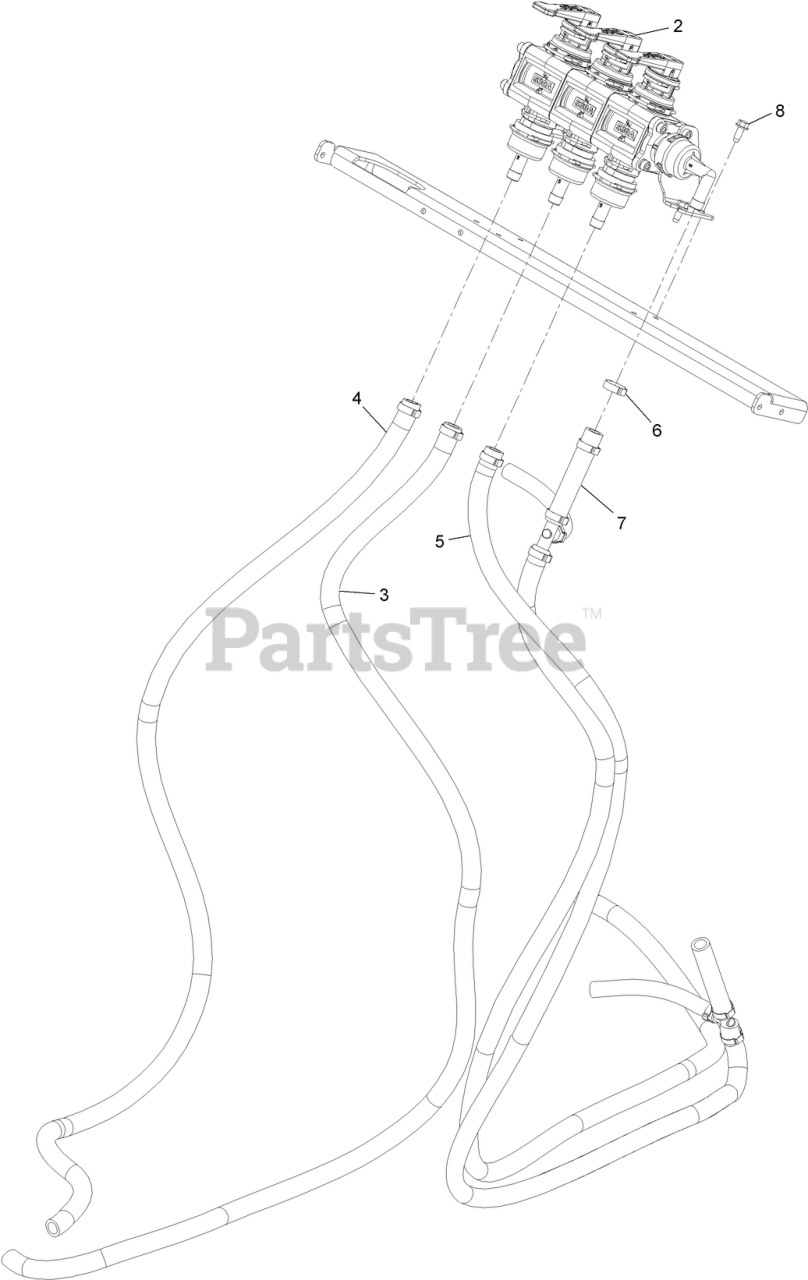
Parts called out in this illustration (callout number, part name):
2	MANIFOLD-VALVE, CONTROL
3	HOSE-WATER
4	HOSE-WATER
5	HOSE ASM
6	CLAMP OETIKER 0.716" CLOSED 0.826" OPEN
7	HOSE ASM
8	SCREW-HWH
